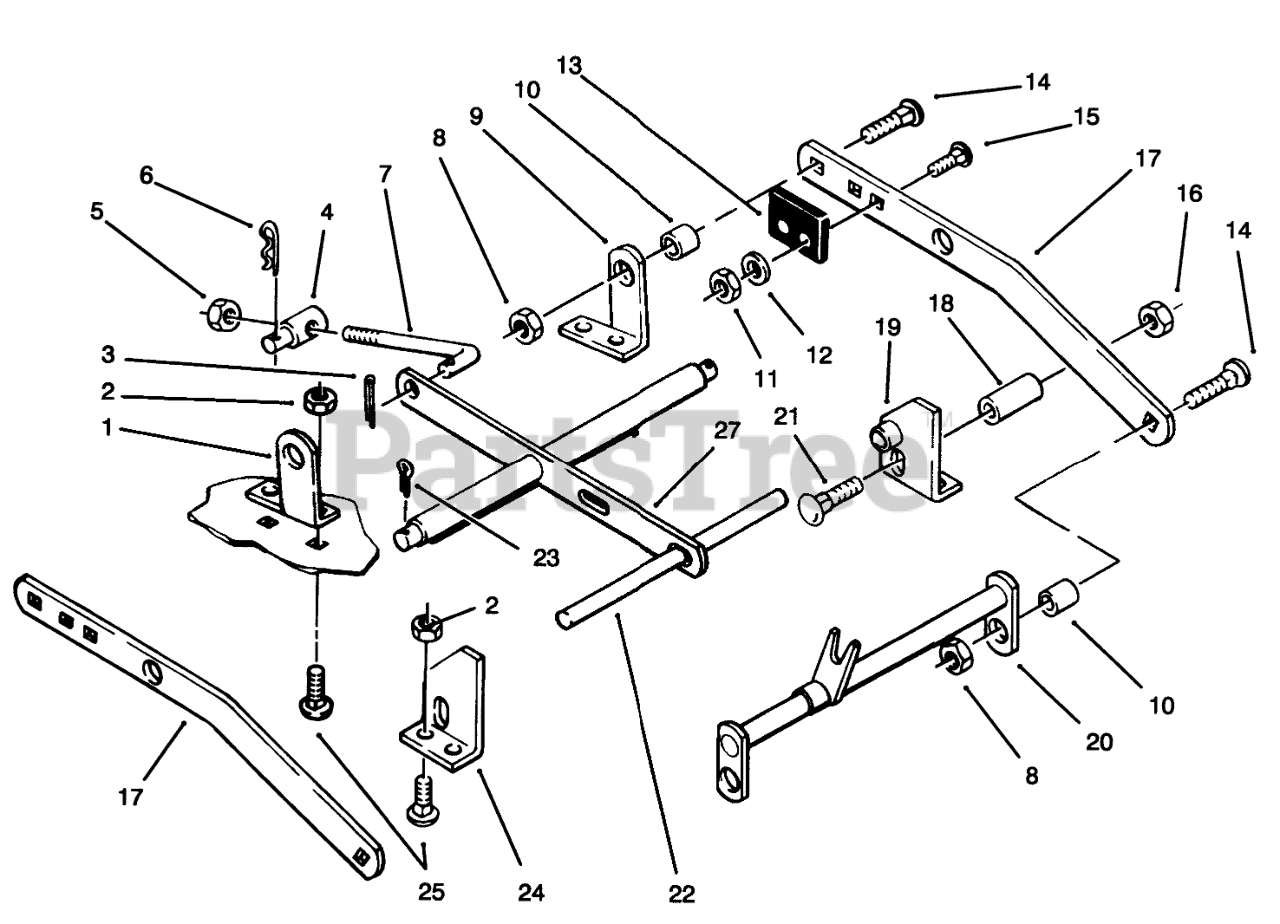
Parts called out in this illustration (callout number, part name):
1	Rear Bracket RH
2	NUT-LOCK, NI
3	PIN-COTTER
4	TRUNNION-LIFT
5	NUT-LOCK, NI
6	Hairpin
7	ROD-LEVEL ADJUST
8	LOCKNUT-FLANGE
9	LH Rear Bracket
10	SPACER
11	NUT-LOCK, NI
12	WASHER-FLAT
13	BUMPER
14	BOLT-CARR
15	SCREW-CARR
16	NUT-LOCK, NI
17	Bar Draft
19	Front Bracket LH
20	Hitch
21	BOLT-CARR
22	Front Shaft
23	PIN-COTTER
24	Front Bracket RH
25	BOLT-CARR
27	Leveler
